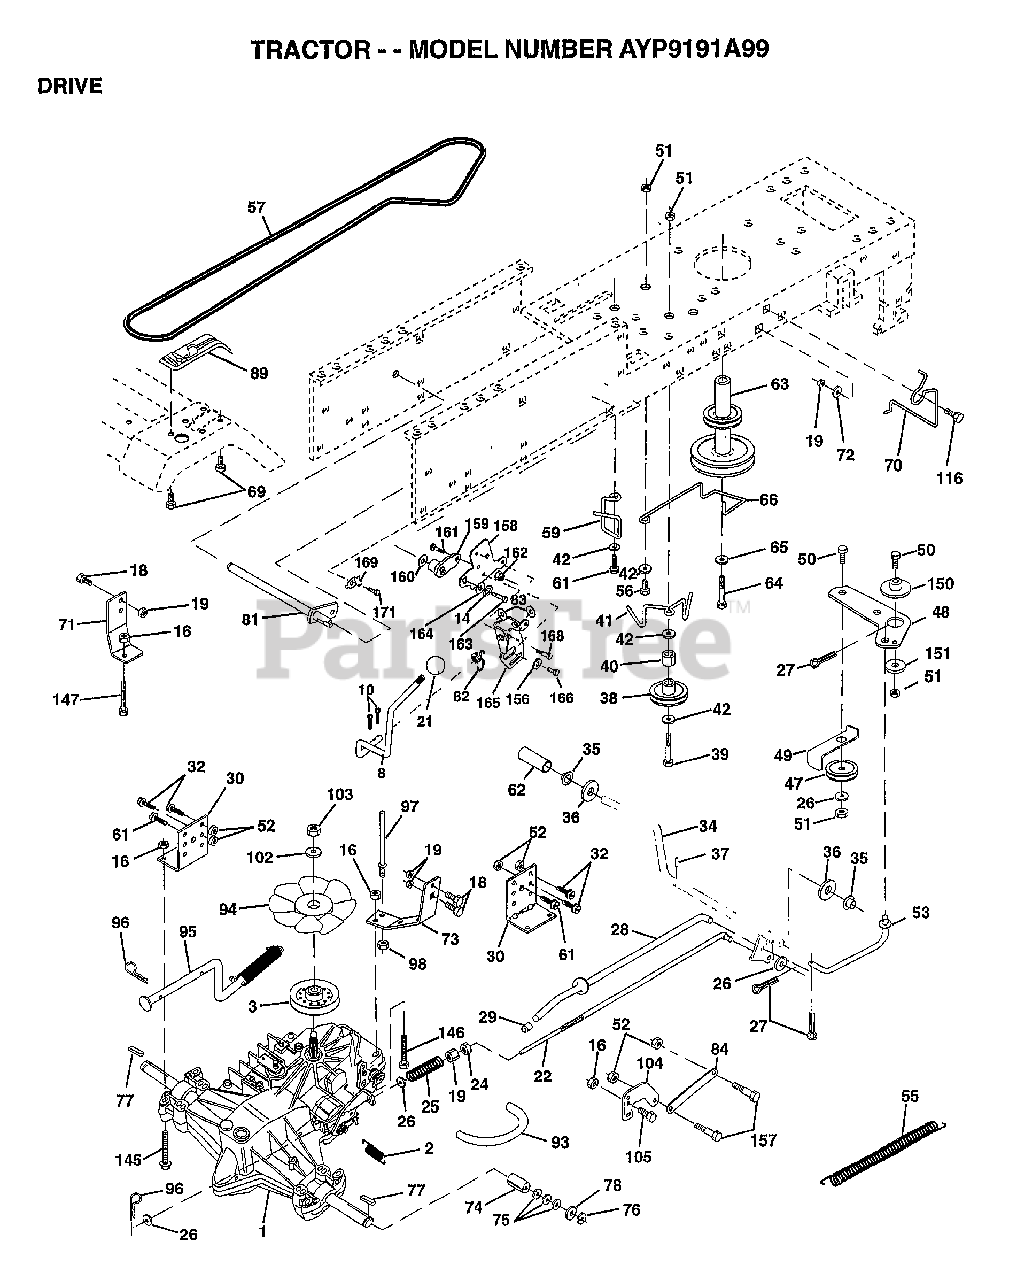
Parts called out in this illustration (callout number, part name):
1	TRANSAXLE.3100650
2	SPRING RET BRAKE
3	PULLEY.TRANSAXLE
8	ROD.SHIFT.FENDER.ADJ.LT.CRD
10	PIN COTTER 1/8
14	LOCKWASHER
16	NUT
18	BOLT
19	NUT
21	KNOB T (1/2-HOLE)
22	ROD.BRAKE.HYDRO.
24	NUT
25	SPRING ROD LT
26	WASHER
27	COTTER PIN
28	ROD.BRAKE.PARK.LT
29	PLUNGER CAP T
30	TRANSAXLE MTG BKT
32	BOLT
34	SHAFT ASM-PEDAL F
35	NYLON BEARING
36	WASHER LT
38	FLAT IDLER PULLEY
39	BOLT
40	SPACER T
41	"KEEPER,BELT.IDLER FLAT"
42	WASHER
43	WASHER T
48	BELLCRANK.CLUTCH
49	RETAIN BELT
53	"LINK, CLUTCH T"
55	"SPRING, RETURN LT"
57	"BELT.GD DRV 82"""
59	KEEPER BELT CNTSP
61	SCREW
62	PEDAL COVER T
63	PULLEY.ENGINE
64	BOLT
65	LOCKWASHER
66	KEEPER-BELT
69	SCREW HEXWSH H-L
70	KEEPER BELT ENG
71	STRAP TORQ LH HYD
72	WASHER
73	"STRAP-TORQUE,RH"
74	SPACER SPLIT
75	WASHER
76	E-RING LT
77	SQUARE KEY
78	WASHER
81	SHAFT.ASM.CROSS
82	"SPRING,TORSION"
83	WASHER
84	LINK.TRANSAXLE.LT/YT
89	CONSOLE.SHIFT.LT
92	HEX BOLT
93	"LINE FUEL HYD 4"""
94	"FAN 7"" HYDRO"
96	RETAINER M
97	BOLT KEEPER RH
98	NUT
102	WASHER BELLEVILLE
104	ARM CONTROL HYDRO
105	SCREW CAP 5/16-18
116	BOLT RDHD 3/8-16
145	BOLT.HEX.FLGHD
146	BOLT.HEX.FLGHD.
147	BOLT.HEX.FLGHD
150	BUSHING.BELLCRANK.GRD.DR
151	WASHER
156	WASHER.SRRTD.5/16
157	"BOLT,SHOULDER"
158	BRKT.SHIFT.MOUNT
159	HUB.SHIFT
160	WASHER
161	BOLT T
164	WASHER.5/8X.281X10GA
165	BRKT.PIVOT.LEVER
166	SCREW.5/16-18X5/8
168	BOLT.SHOULDER.5/16-18X.561
169	PLATE.FASTENING
171	SCREW LT
